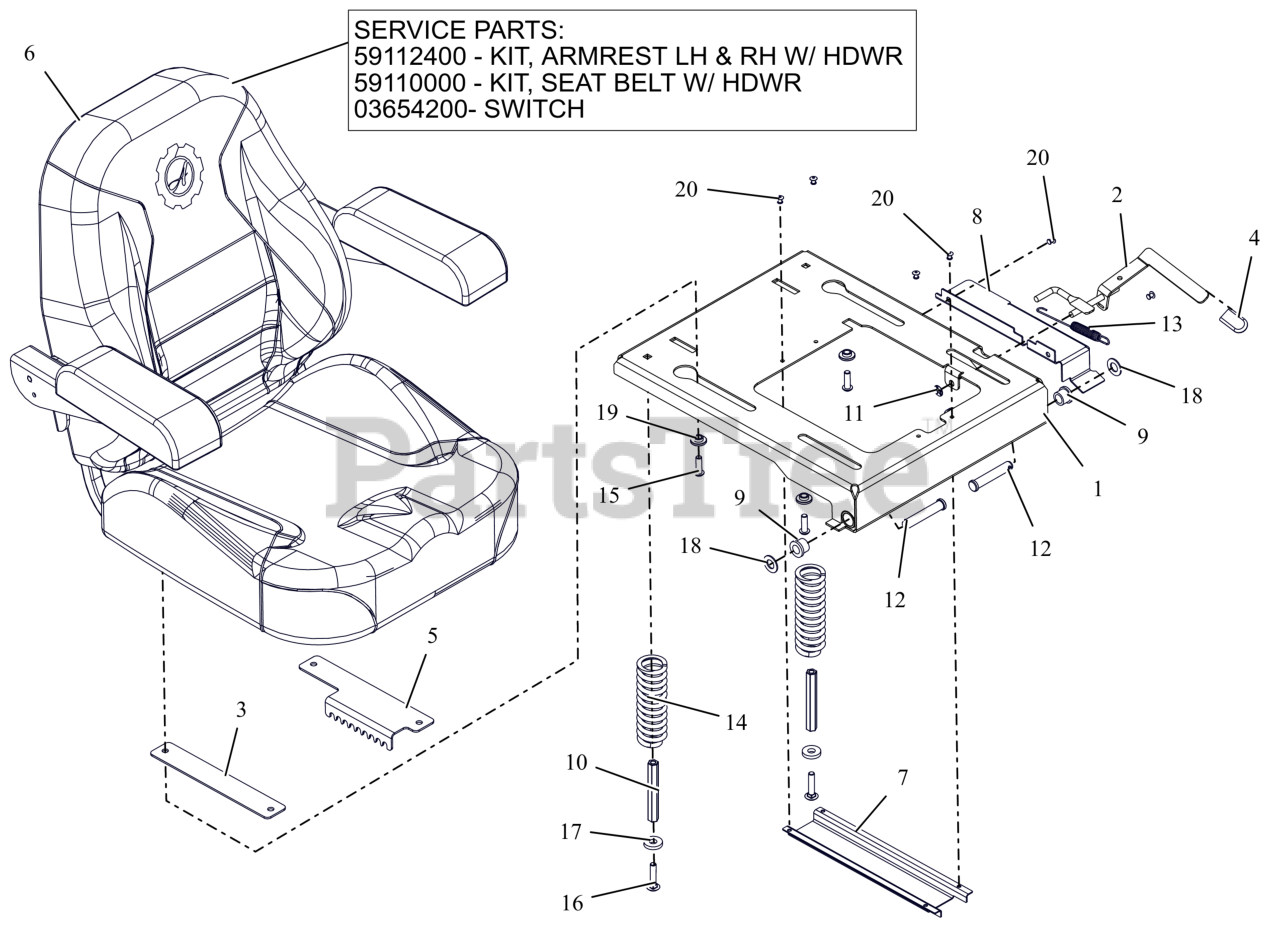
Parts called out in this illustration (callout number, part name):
1	WLDMT, SEAT PLATE HD
2	WLDMT, SEAT SLIDE LEVER
3	PLATE, ADJUSTABLE SEAT SLIDE
4	GRIP, SEAT LEVER, GREY
5	PLATE, HD SEAT ADJUSTMENT
6	SEAT, APEX
6	KIT-LH & RH ARM REST-05124700
6	KIT-SEAT BELT REPLACE-05007300
6	SWITCH- SEAT
7	GUARD,SEAT SWITCH
8	GUARD, SEAT PLATE CE
9	BSHG, FLG .516X.750X.625X.937
10	NUT, COUPLING 5/16X18 X 3.75
11	NUT-PUSH .312
12	PIN-CLIC .50X2.70X2.31 -ZCC
13	SG-TENS .06X.482X5.35
14	SPRING, COMPRESSION SEAT 224LB
15	BLT,SHCS-BTN .31-18X1.00 ZCC
16	BLT,RHSN .31-18X1.50 G5 ZCC
17	WSHR, FLT .406X1.00X.188 ZCC
18	WSHR, FLT .531X1.00X.063 ZCC
19	BSHG-FLG .325X.499X.3X.875
20	RIVET, .1875 AL/AL .126-.250
